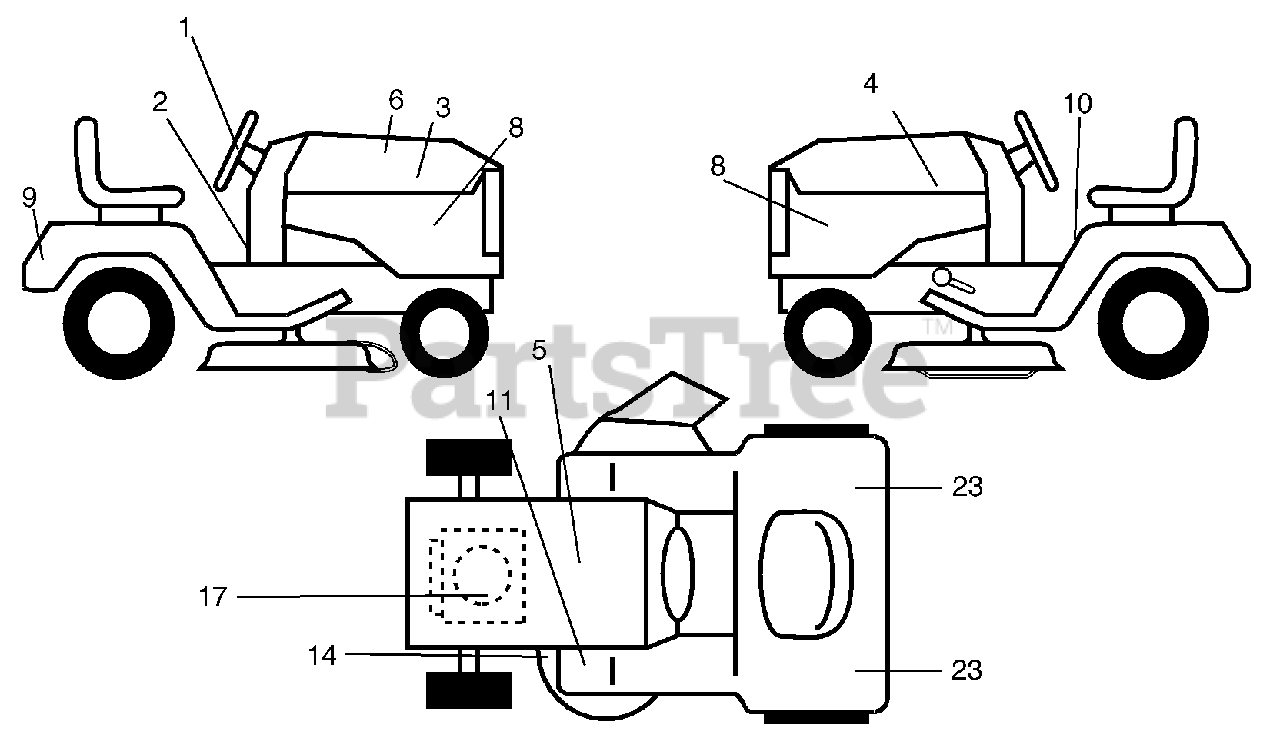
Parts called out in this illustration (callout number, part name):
1	Decal Steering Wheel
2	Decal, Dash
3	Decal, Hood, RH
4	Decal, Hood, LH
5	Decal, Battery DNGR/PSN
8	Decal, SD, PNL
9	Decal, Fender
10	Decal, Fender Danger
11	Decal, Clutch/Brake
14	Decal, V-Belt Schematic
17	Decal, Engine
23	Reflector, Taillight
